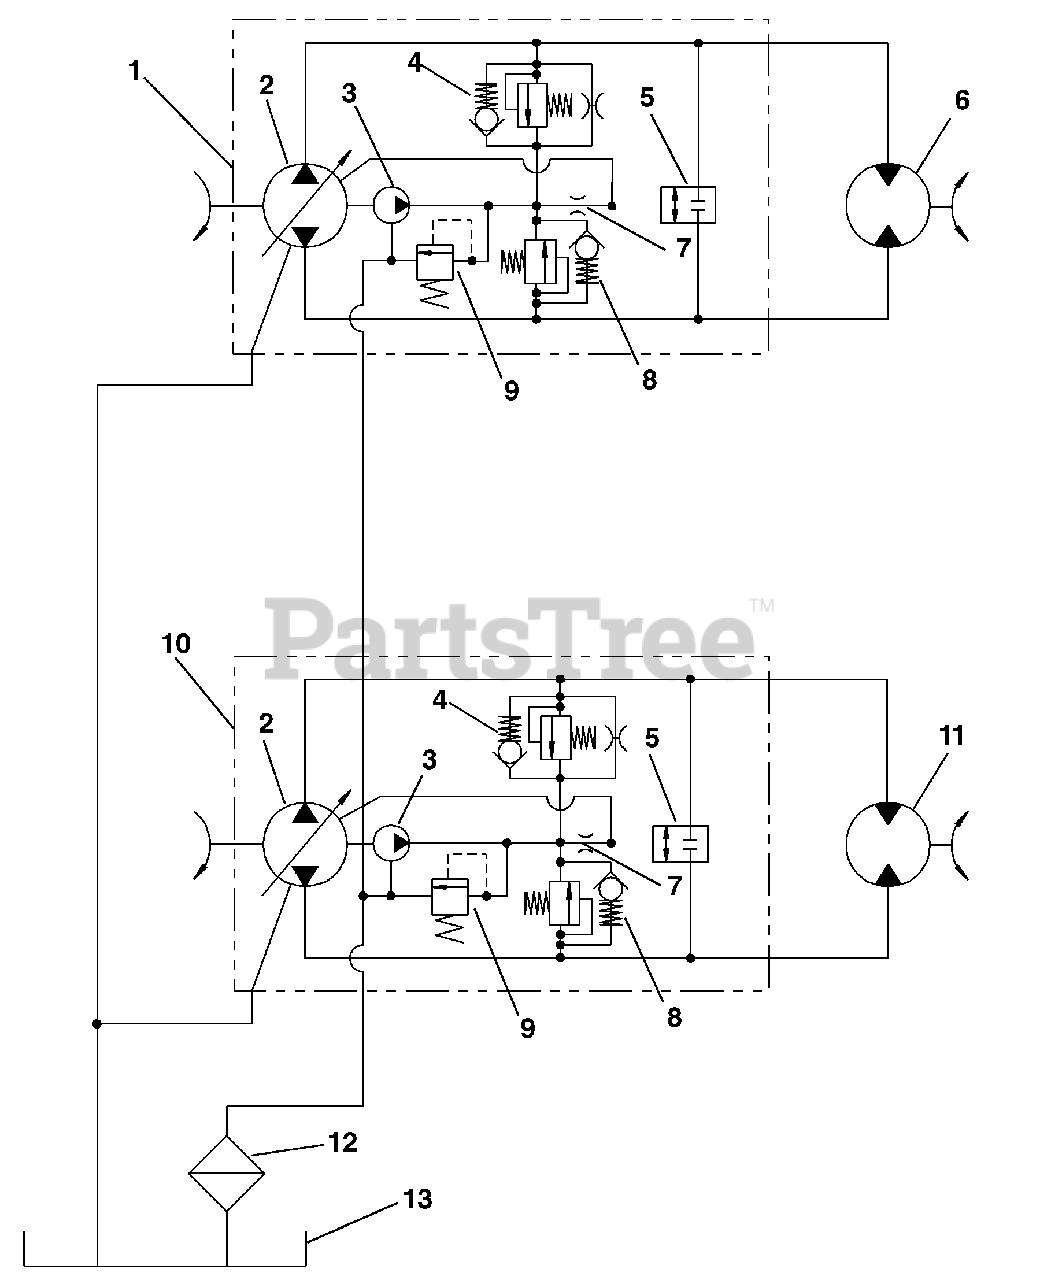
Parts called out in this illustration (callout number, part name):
1	Left Hydrostatic Pump Assembly
2	Pump Block
3	Charge Pump
4	System Change Check Shock Valve (Reverse)
5	Manual Bypass
6	Left Wheel Motor
7	Cooling Orifice
8	System Change Check Shock Valve (Forward)
9	Charge Relief Valve
10	Right Hydrostatic Pump Assembly
11	Right Wheel Motor
12	Inlet Filter
13	Hydraulic Reservoir
